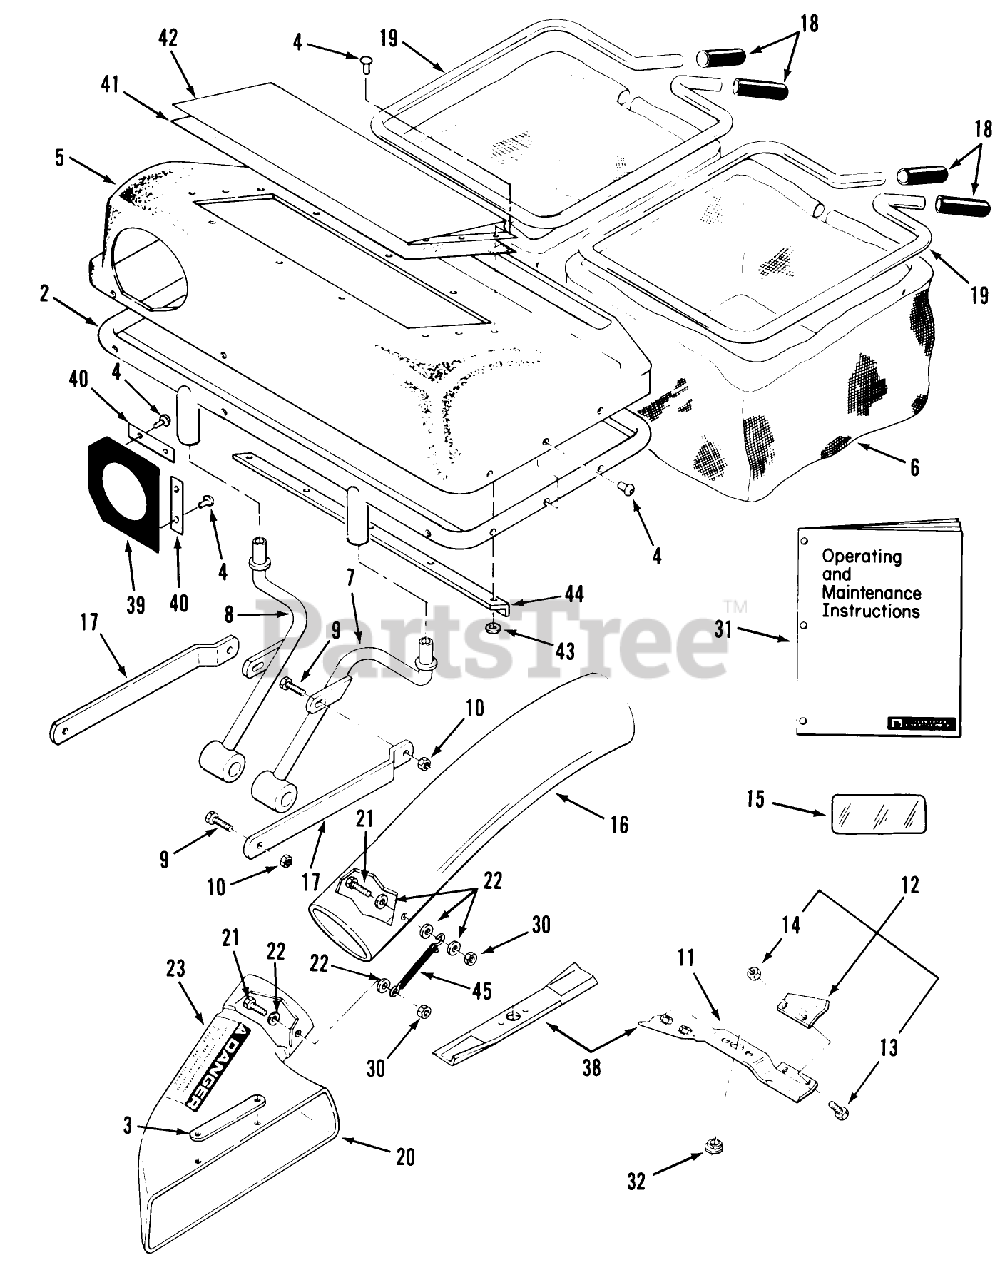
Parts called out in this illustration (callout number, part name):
3	PLATE-ELBOW *B
4	RIVET-BLIND
7	ASSY QUICK ATTACH *B
11	ASSY-HI LIFT BLADE
12	S/A 37 LIFT TAB KIT
13	BOLT 5/16-18X5/8
14	NUT-HEX
15	DECAL-OVERLAY
18	GRIP
31	Operating and Maintenance Instructions
32	SPACER BLADE
38	KIT-BLADE (SERVICE)
